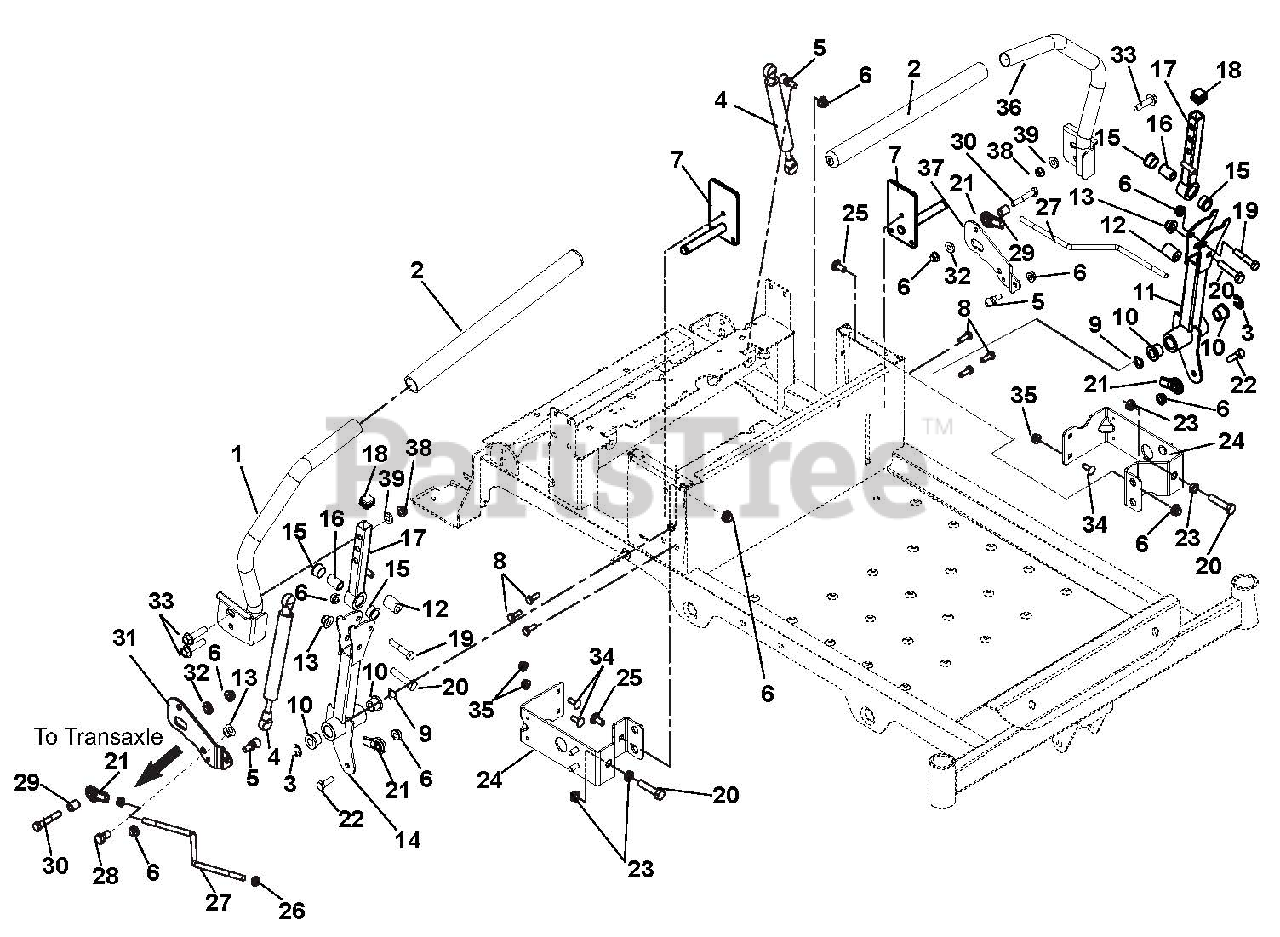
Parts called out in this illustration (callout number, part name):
1	WMT, STEERING HANDLE
2	GRIP, HANDLEBAR 15" FOAM
3	RG-RTNG-EXT .500X.042 (E)
4	DAMPER, STABILUS
5	STUD- BALL
6	@NUT-LK-NYL-FLG .31-18 YWZC
7	WMT, STEERING SHAFT
8	SCR-TAP .25-20X.50 HWH TR YWZ
9	WSHR-WAVE .50X.75X.015 .13FRHT
10	BSHG-FLG .500X.750X.625X.937
11	WMT, LOWER CONTROL ARM
12	BSHG, ECCENTRIC .328X.750X.970
13	@NUT-LK-NYL-FLG .38-16 YWZC
14	WMT, LOWER CONTROL RH
15	BSHG-FLG, .625X.75X.450X.875
16	SPACER, .375X.625X.970 (PM)
17	WMT, UPPER CONTROL ARM
18	CAP PLUG, SQ 3/4-14-20 RIBBED
19	@BLT-HEX .31-18X1.75 GR5 YWZC
20	BLT-HEX .375-16X1.750 FTD YWZC
21	ALIGNABALL, 5/16 RH THREAD
22	@BLT-HEX .31-18X1.00 GR5 YWZC
23	NUT-HEX-JAM .375-16 YWZC
24	WMT, STEERING STOP
25	@BLT-RHDSSQNK .31-18X.75 G5YZ
26	NUT-JAM .31-24 YWZC
27	WIREFORM, STEERING LINK
28	@BLT-HEX .38-16X.75 GR5 YWZC
29	SPACER, .328X.500X.625
30	@BLT-HEX .31-18X2.00 GR5 YWZC
31	PLATE, DAMPER RH
32	BSHG-FLG .316X.430X.225X.750
33	BLT-SERHFWH .375-16X1.25 YWZC
34	@BLT-RDHDSQNK .25-20X.75 G5YZ
35	@NUT-LK-NYL-FLG .25-20 YWZC
36	WMT, STEERING HANDLE LH
37	PLATE, DAMPER (LH)
38	@NUT-LK-CTR-JAM .375-16 YWZC
39	@WSHR-FL-STL.406X.812X.065 YWZ
